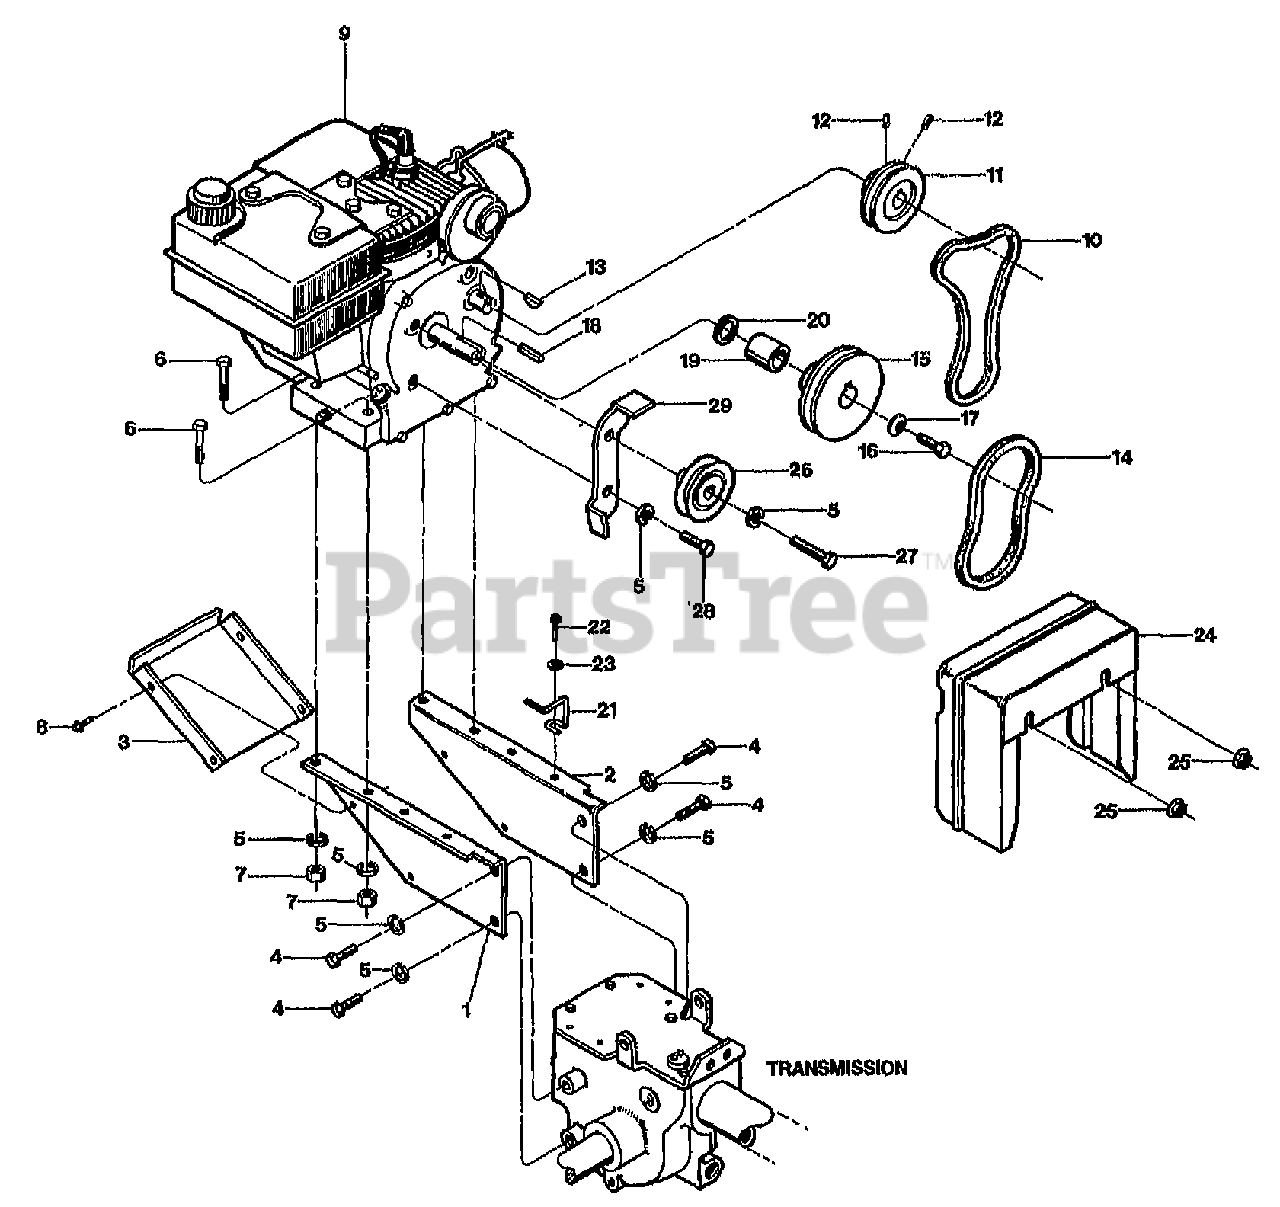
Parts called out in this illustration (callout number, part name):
1	BRKT-ENG LT P4
2	BRKT-ENG RT PNT
3	PAN-ENG BRKT PNT
4	SCR-HHC 5/16-18X.75 GR 5 (Brackets to Transmission)
5	WASHER-LK .312 ZP
6	SCR-HH 5/16-18X1.5 G5 ZP
7	NUT-HEX 5/16-18 ZP
8	SCR-HH SEMS 10-32 X .5 ZP (Sems w/ permanent washer.)
9	Tecumseh, Model H35, Type 45593S
9	Tecumseh, Model H35, Type 45606S
10	BELT-V (Reverse; see V-Belt Set #11018)
11	PULLEY-REVERSE MACH (Engine driven, 1 groove, single belt.)
12	SCR-SS 1/4-20 X .25 (Secures reverse engine pulley.)
13	KEY-WOODRUFF #5 (Reverse pulley to reverse PTO shaft)
14	BELT-V GROOVE FWD SMFRAME (See V-Belt Set #11018)
15	PULLEY-ENGINE MACH (Engine driven, 1 groove single belt)
16	SCR-HH 3/8-24X1.0 G5 ZP (Attaches forward pulley)
17	WASHER-.994X.413X.145 (disc spring; concave surface faces forward pulley.)
18	KEY-.188 SQX1.0 (Forward pulley to forward PTO shaft)
19	SPACER-.755X.937X1.375 (on forward PTO shaft between shim and forward pulley.)
20	SHIM-1.0X.7656X.031 (On forward PTO shaft between Engine and spacer.)
21	GUIDE-BELT FWD
22	SCR-HWH 1/4-20 X .75 STH
23	WASHER-FLAT 1/4 SAE
24	COVER - Shields belts and pulleys
25	NUT-HFLK 5/16-18 ZP
26	IDLER-V-GROOVE (Reverse Idler (Internal bushing type)
27	BOLT-HH 5/16-24 X 1.5 ZP
28	SCR-HH 5/16-24X.50
29	GUIDE-BELT REV PNT
